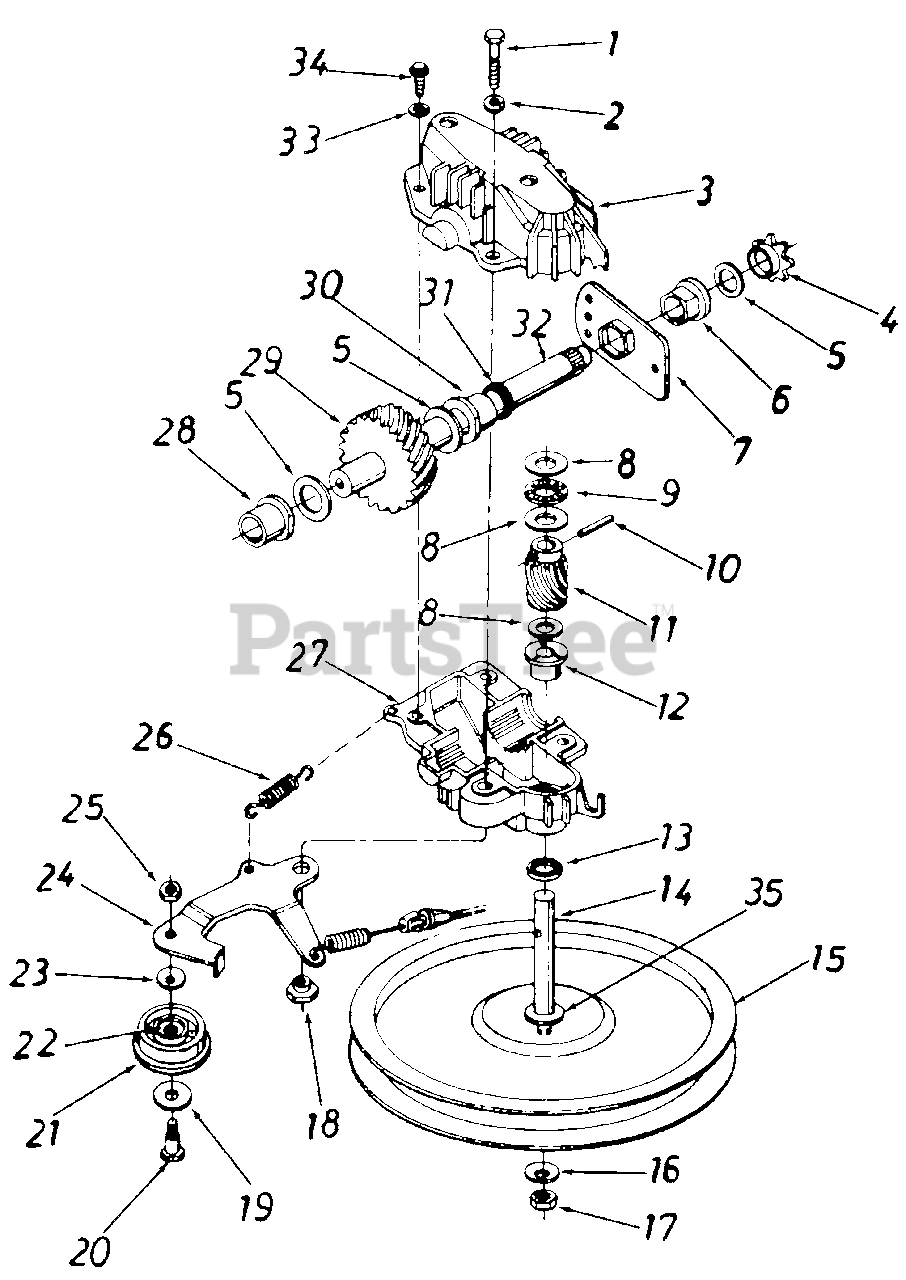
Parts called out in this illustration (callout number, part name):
1	Hex Bolt 1/4-20 x 1.25" Lg.*
2	L-Wash. 1/4" I.D.*
3	Upper Transmission Hsg. Half
4	#48 Sprocket 7 Tooth x 1/2 0 Pitch
5	Fl-Wash. 5/8" I.D. x .030
6	Hex Flange Brg. .631" I.D.
7	Hex Bearing Cup
8	Thrust Wash. .382" I.D. x .70" O.D.
9	Thrust Bearing .375" I.D. x .812" O.D.
10	Spring Pin Spir. 1/8" x .62" Heavy
11	11 Tooth Helical Gear
12	Flange Bearing
14	Pulley-Transmission Shaft .375 O.D.
15	Fl-Pulley 5.06" O.D.
16	Bell-wash. .265" I.D. x .75" O.D.
17	Hex Lock Nut 1/4-28 Thd
18	Shld. Spacer .375" Dia. x . 170
19	Fl-Wash. .390" I.D. x 1.0" O.D.
20	Shld. Bolt .375" Dia. x .40"
21	Fl-ldler Plastic 1.50" Dia. x .48
22	Needle Brg. .375" x .31
23	Bell-Wash. .265" I.D. x .75" O.D.
24	Idler Brk't. Ass'y.
25	Hex Patch L-Nut 1/4-28 Thd.
26	Extension Spring 1.12" Lg.
27	Lower Transmission Hsg. Half
28	Flange Bearing .566 Dia.
29	33 Tooth Helical Gear
30	Flange Bearing .629 Dia.
31	Oil Seal .625 Dia.
32	Gear Sprocket Shaft
34	Hex B-Tap Scr. #10 x .62"
35	Hex Washer .26" x .88" x .04"
